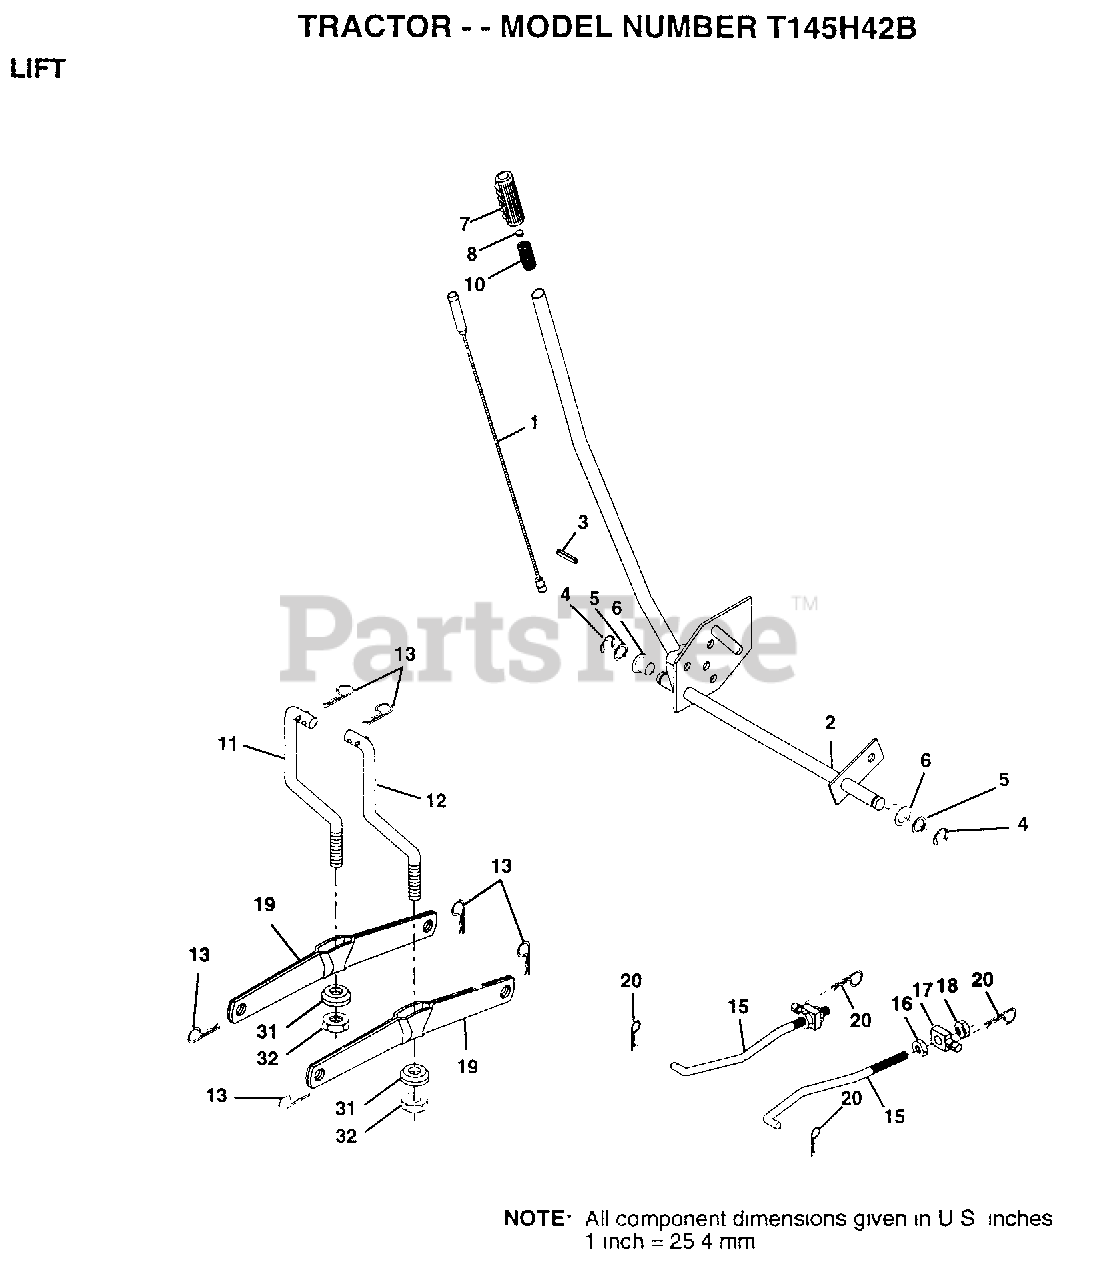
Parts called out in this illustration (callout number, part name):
1	WIRE ASM
2	HANDLE.LIFT.LH.
3	PIN GROOVE
5	WASHER
6	NYLON BEARING
7	GRIP
15	LINK.FRONT
16	NUT
17	TRUNION
18	NUT.LK.W/WSH.1/2.
19	ARM SUSP REAR
20	RETAINER.SPRING
31	BEARING PVT LH
32	NUT.CROWNLOCK.3/8
